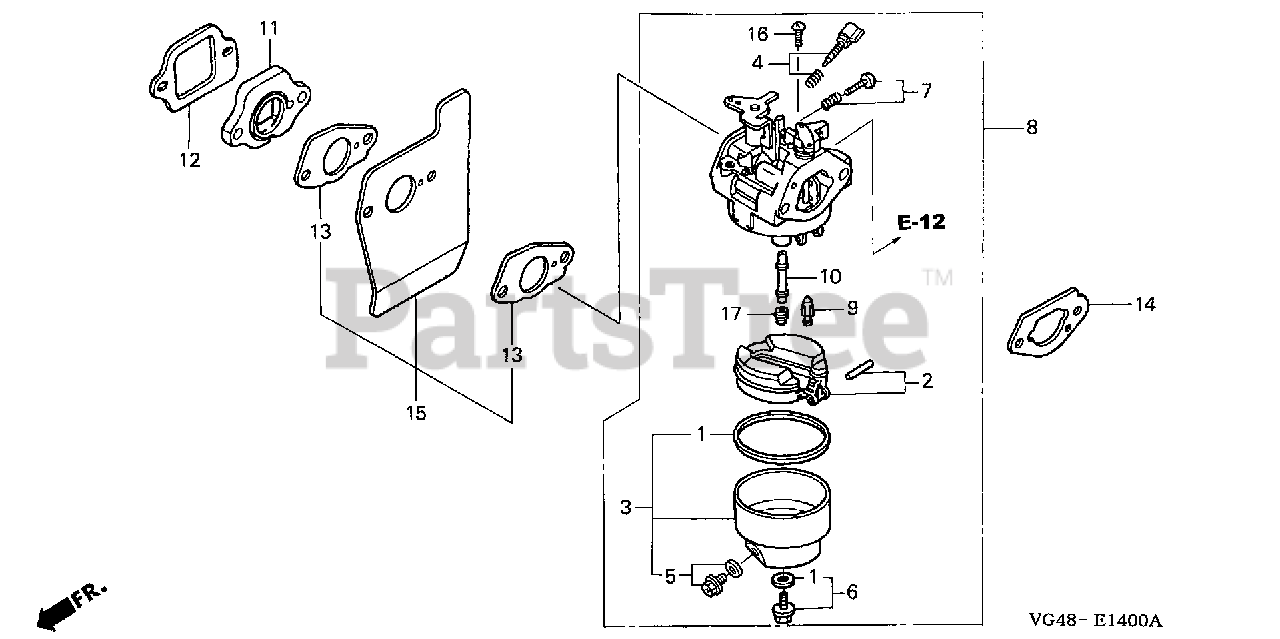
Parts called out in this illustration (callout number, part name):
1	GASKET SET
3	CHAMBER SET, FLOAT
5	SCREW SET, DRAIN
6	SCREW SET
7	SCREW SET (THROTTLE STOP)
8	CARBURETOR ASSY. (BB62B D)
8	CARBURETOR ASSY. (BB62B E)
8	CARBURETOR ASSY. (BB62W B)
8	CARBURETOR ASSY. (BB62W C)
9	VALVE, FLOAT
10	NOZZLE, MAIN
11	INSULATOR, CARBURETOR
12	GASKET, INSULATOR
13	GASKET, CARBURETOR
14	GASKET, CARBURETOR
15	GUIDE, AIR
16	SCREW, PAN (5X6)
17	JET, MAIN (#60)
17	JET, MAIN (#62)
17	JET, MAIN (#65)
